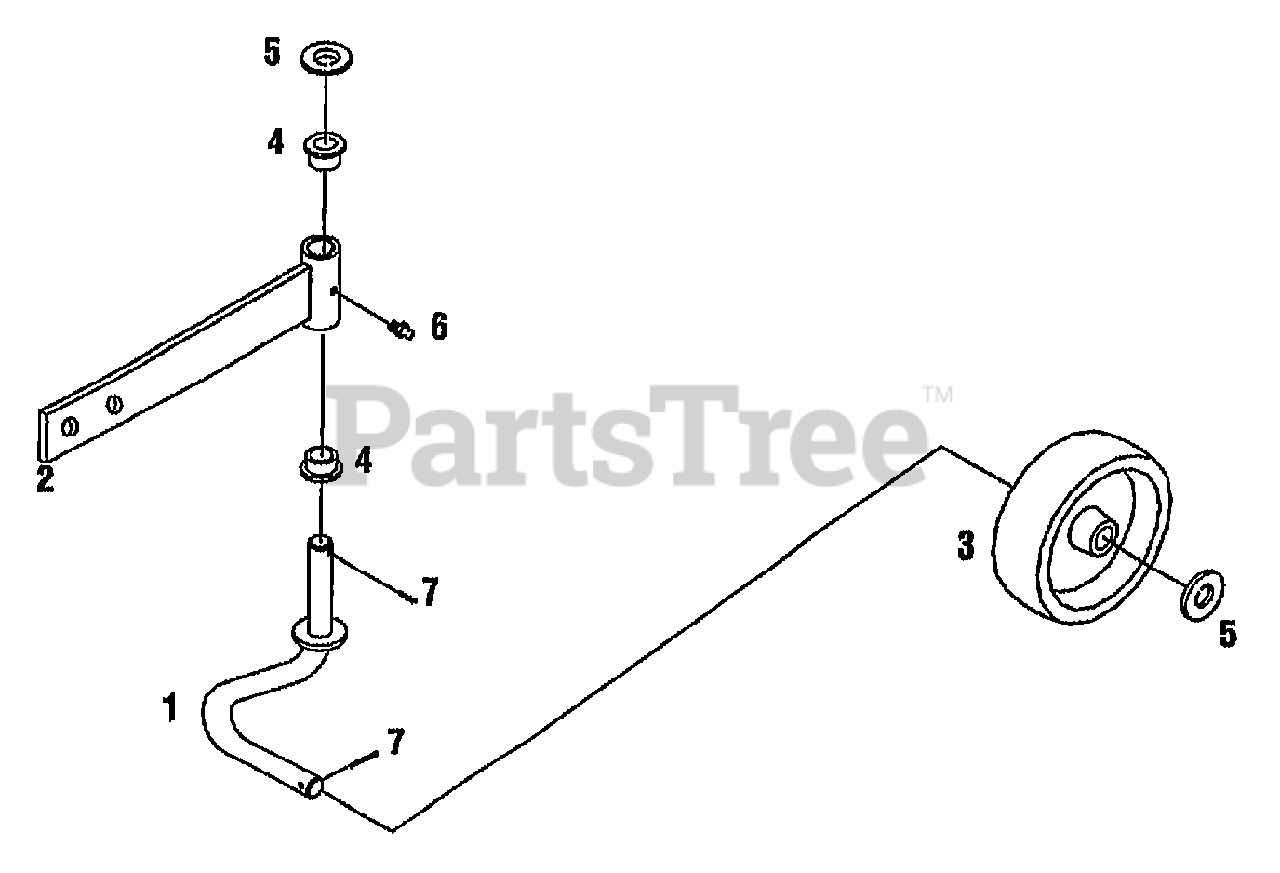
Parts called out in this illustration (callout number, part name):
1	ASSM-SPINDLE
2	SUPPORT-WHEEL WELDED
3	GAUGE-WHEEL
4	BUSHING (WAS #1742133)
5	WASHER-1.25X.765X.049
6	FITTING-GREASE 1/4-28X2.00
7	PIN-COTTER .125X1.5
